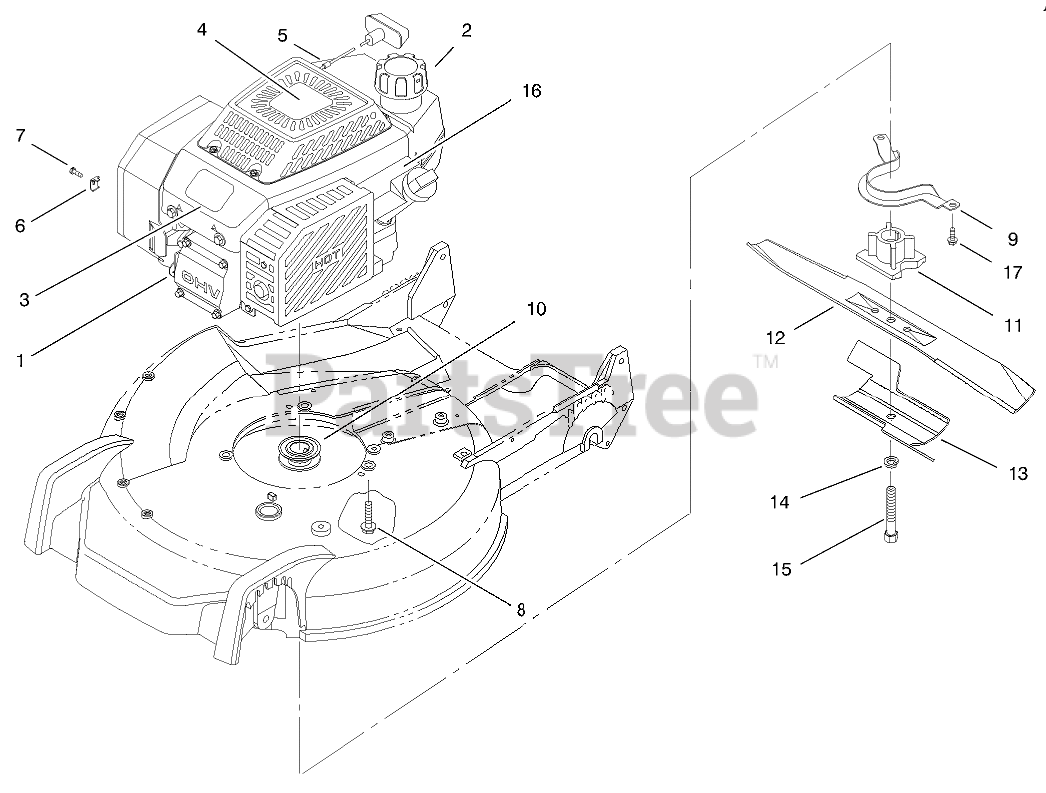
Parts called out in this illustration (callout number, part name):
1	Engine
2	CAP-GAS
3	PLATE-LOGO
4	DECAL - ENGINE
5	STOP-ROPE
6	CLAMP-CASING
7	CLAMP SCREW F/W ENGINE
8	SCREW-HWH
9	Guide-Belt
10	PULLEY-DRIVE, ZONE START
11	RETAINER - BLADE
12	Blade
13	Stiffener-Blade
14	WASHER-LOCK
15	SCREW-BLADE
16	COVER - BRAKE F/W
17	SCREW-HWHTF
